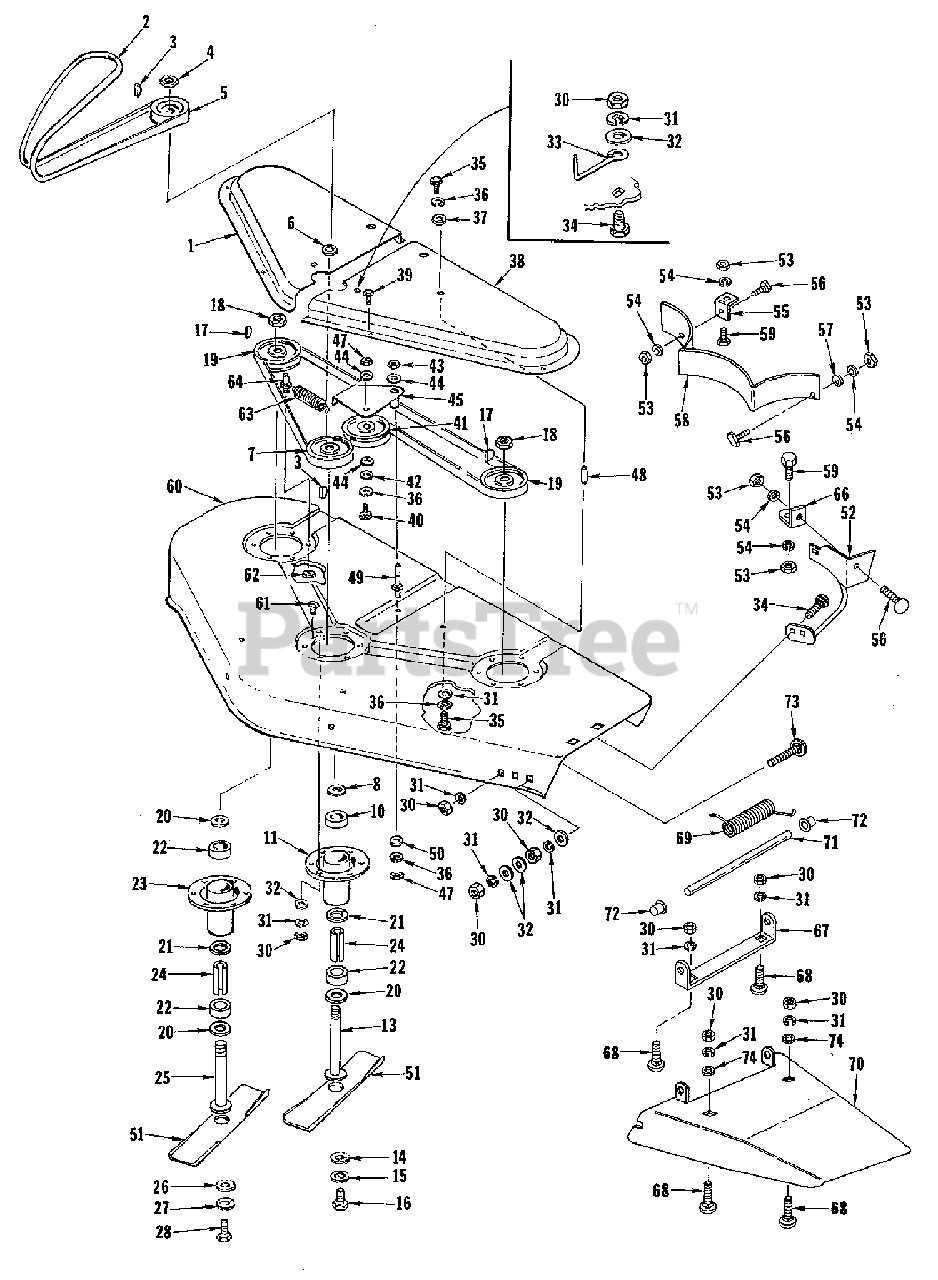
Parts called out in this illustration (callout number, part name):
1	SHIELD, Arbor (R.H.)
2	BELT, Front PTO Drive
3	KEY, Woodruff, #61
4	NUT, Hex Jam, 3/4-16
5	PULLEY, Corss Drive
6	WASHER, Flat
7	PULLEY, Mower Spindle
8	WASHER, Special
9	RING, Backing
11	TUBE ASSEMBLY, Arbor
13	ARBOR ASSEMBLY, Drive
14	WASHER, Belleville
15	WASHER, Shoulder
16	SCREW, Hex Cap (L.H. Thread) 1/2-20 x 1-1/2
17	KEY, Woodruff, #61
18	NUT, Hex Jam, 3/4-16
19	PULLEY, Mower Spindle
20	WASHER, Special
21	RING, Backing
23	TUBE ASSEMBLY, Drive
25	ARBOR ASSEMBLY, Drive
26	WASHER, Belleville
27	WASHER, Shoulder
28	SCREW, Hex Cap, (L.H. Thread) 1/2-24 x 1-1/2
30	NUT, Hex, 5/16-18
31	WASHER, Lock, 5/16"
32	WASHER, Flat, 5/16
34	BOLT, Carriage, 5/16-18 x 3/4
35	SCREW, Hex Cap, 3/8-16 x 3/4
36	WASHER, Lock, 3/8
37	WASHER, Flat, 3/8
38	SHIELD, Arbor (L.H.)
39	SCREW, Hex, Taptite, 1/4-20 x 3/8
40	SCREW, Hex Cap, 3/8-16 x 1-1/2
41	PULLEY, Idler
43	NUT, Hex, 3/8-16
44	WASHER, Flat
45	LEVER ASSEMBLY, idler
46	BELT, Arbor Drive
47	NUT, Hex, 3/8-16
48	SPACER, Threaded
50	WASHER, Flat
51	BLADE, Mower, 32"
51	BLADE, Mower, 36"
52	GUARD DISCHARGE
53	NUT, Hex, 1/4-20
54	WASHER, Lock, 1/4
55	CLIP, Baffle
56	BOLT, Carriage
57	WASHER, Flat, 1/4
58	BAFFLE, Mower, 32"
58	BAFFLE, Mower, 36"
59	SCREW, Hex, Cap, 1/4-20 x 5/8
60	HOUSING, Mower, 32"
60	HOUSING, Mower, 36"
61	SCREW, Hex Cap, 5/16-18 x 3/4
62	NUT, Hex Jam, 5/16-18
63	SPRING, Idler
64	STUD, Idler Spring
65	SCREW, Hex Cap, 3/8-16 x 1
66	CLIP, Baffle
67	SUPPORT, Hinge
68	BOLT, Carriage, 5/16-18 x 5/8
69	SPRING, torsion
72	FASTENER, Pushnut
73	BOLT, Carriage, 5/16-18 x 1-1/4
74	WASHER, Special
